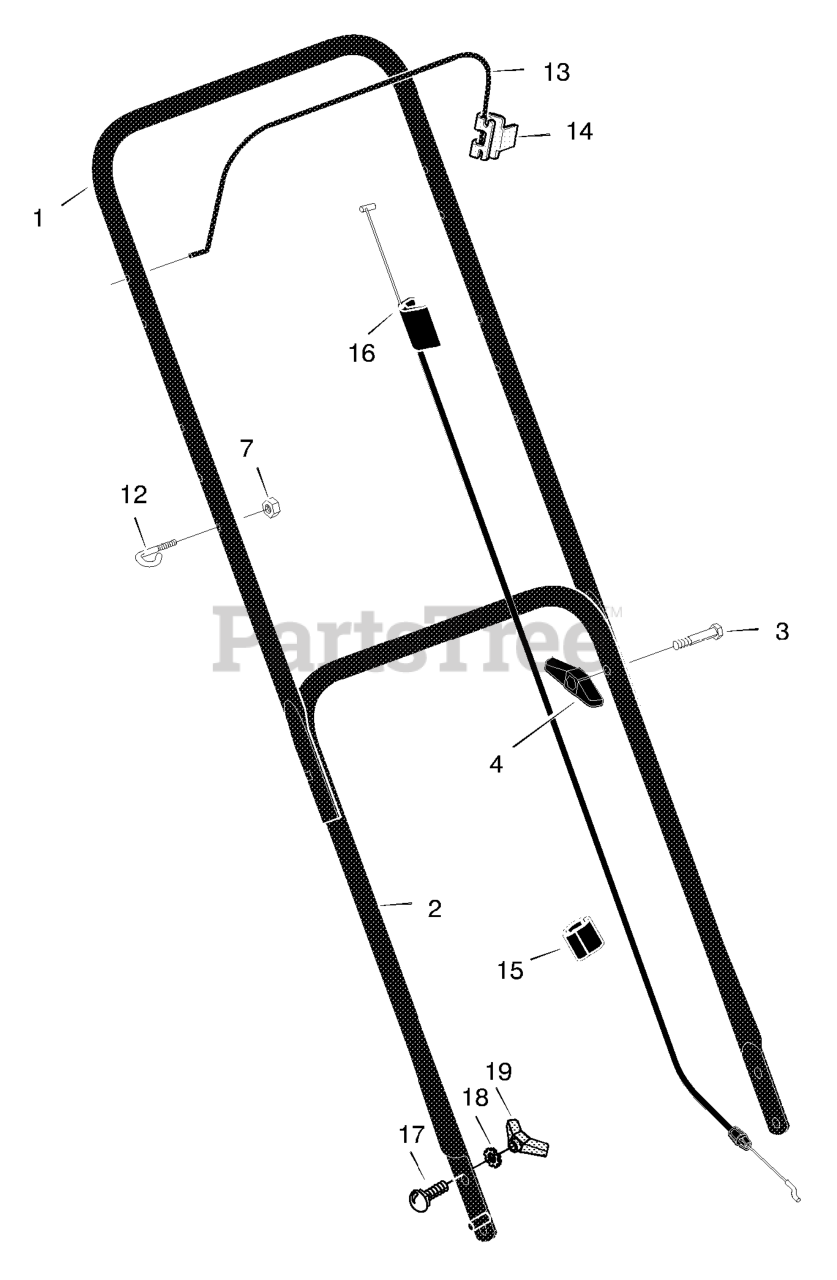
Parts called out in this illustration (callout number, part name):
1	Handle, Upper (Black)
2	Handle, Lower (Black)
4	Knob, Plastic
7	Locknut
12	Guide, Rope
13	Engine Stop Lever
14	Bracket, Stop Lever
15	Clip, Cable
16	Engine Stop Cable
17	Bolt, Carriage
19	Knob, Plastic
